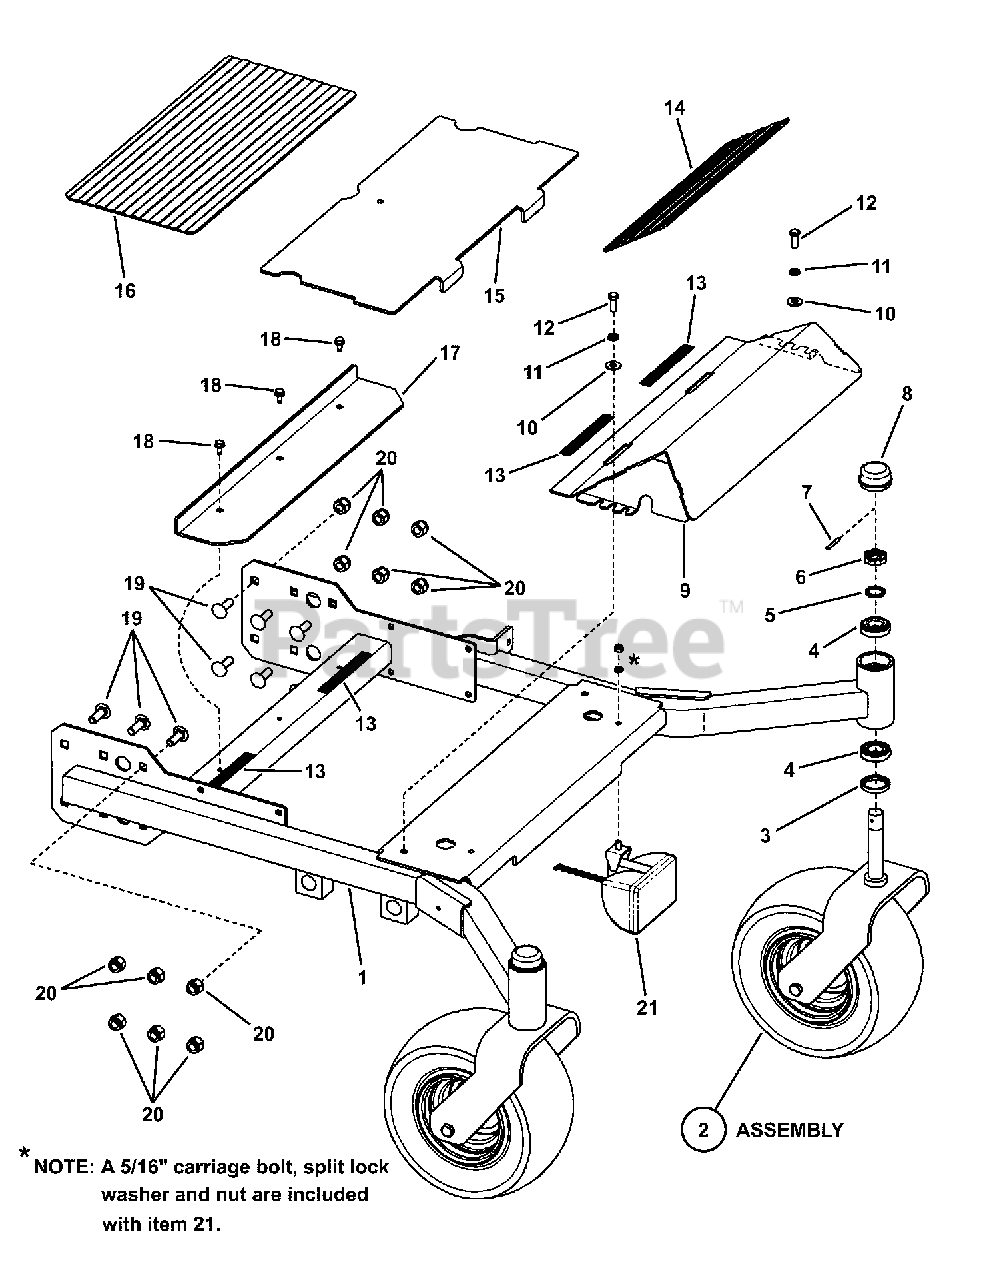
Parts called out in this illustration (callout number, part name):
1	WELDMENT, Front Frame
2	GROUP, Front Wheel
3	GREASE SEAL
4	BEARING, Tapered Roller
5	SPACER, Jackstaff
6	CASTLE NUT, 1-1/ UNF, GR B
7	ROLL PIN, 3/16 x 1-1/2"
8	CAP, Dust
9	WELDMENT, Foot Pedestal
10	WASHER, 3/8" USS
11	WASHER, 3/8" Split Lock
12	BOLT, 3/8-16 X 1" GD5 CZ
13	PAD, Floor Board Support
14	FLOOR MAT, Top
15	FOOTPAN
16	FOOTPAN, Mat
17	FOOT STAND, LFNZM
18	SCREW, 5/16-18 x 5/8" Hex Washer Self-Tap
19	BOLT, 1/2-13 x 1-1/2" Square Neck Carriage, GR 5
20	NUT, 1/2-13 Hex Nyloc
21	HEADLIGHT, w/Connectors
